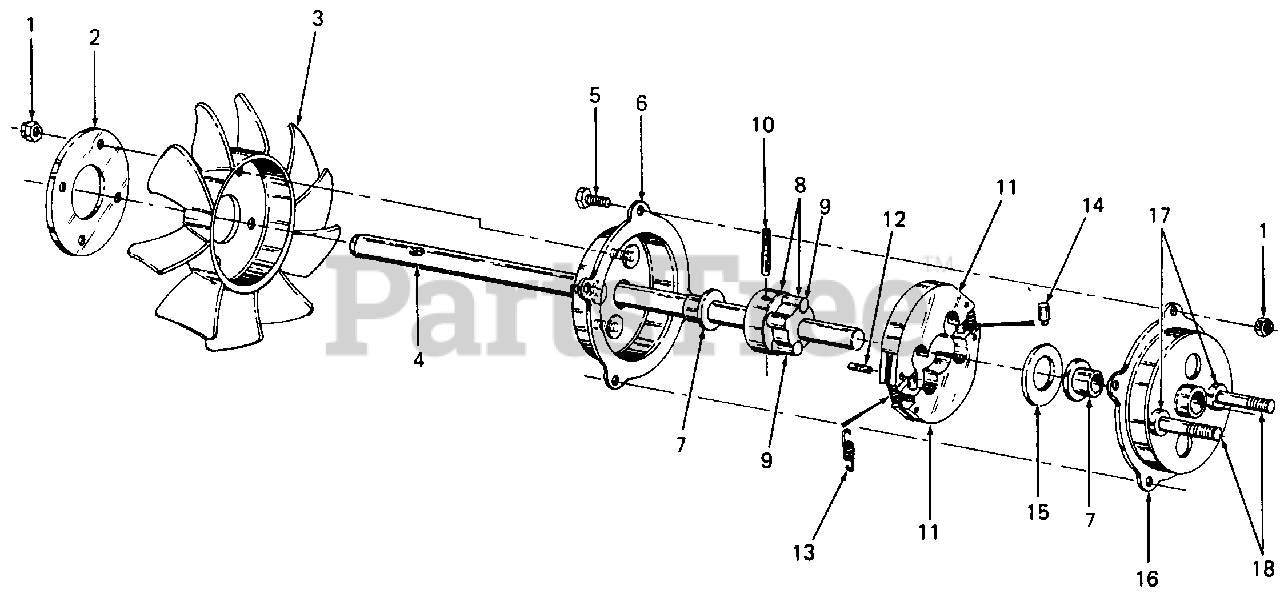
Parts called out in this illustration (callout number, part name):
1	Nut, Hex Patch Lock, 1/4-20
2	Spacer, Fan
3	Fan, Cooling
4	Shaft, Drive
5	Screw, Hex Cap, 1/4-20 X .50 Lg GR5
6	Cover Assy, Clutch
7	Bearing, Flange, .630 ID
8	Hub Assy, Clutch
10	Pin, Slotted Roll, 1/4 Dia X 2.25 Lg
11	Shoe Assy, Clutch
12	Pin, Spirol Spring, 1/8 Dia X 5/8 Lg
13	Spring, Extension, .31 Dia X .85 Lg
15	Washer, Flat, .635 X 1.585 X .062 Thk HDN
16	Housing, Clutch
17	Spacer, .385 X .88 X .25 Lg
18	Bolt, Ribbed Neck, 3/8-24 X 1.5 Lg GR5
